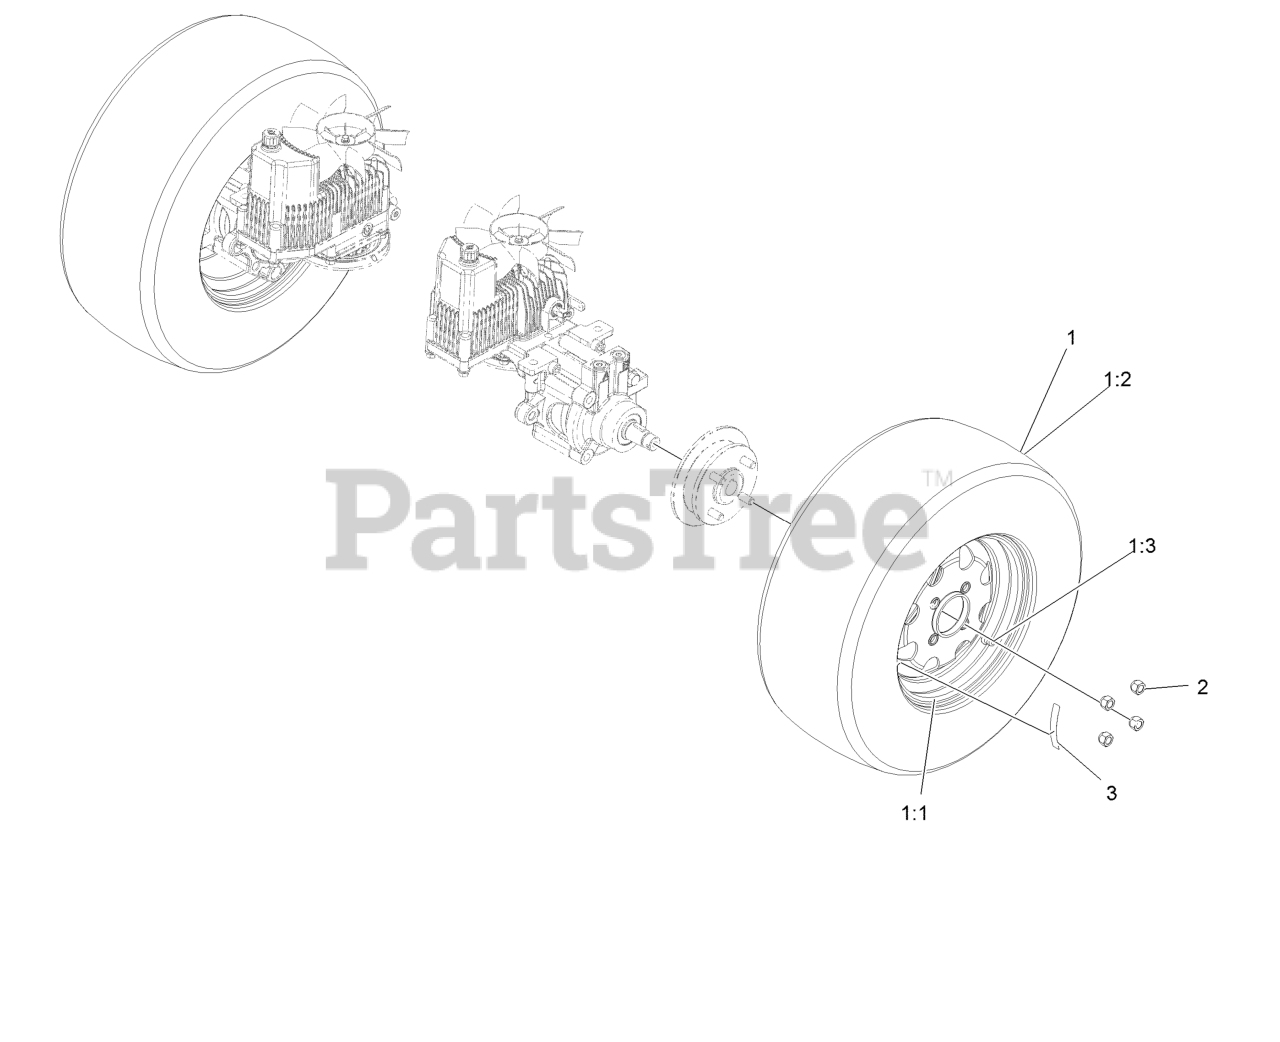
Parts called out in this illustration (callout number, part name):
1	Wheel And Tire ASM
1:1	Rim ASM
1:2	Tire
1:3	Stem-Valve
2	Nut-Lug 1/2-20
3	Decal-Torque, Wheel Hub Lug
